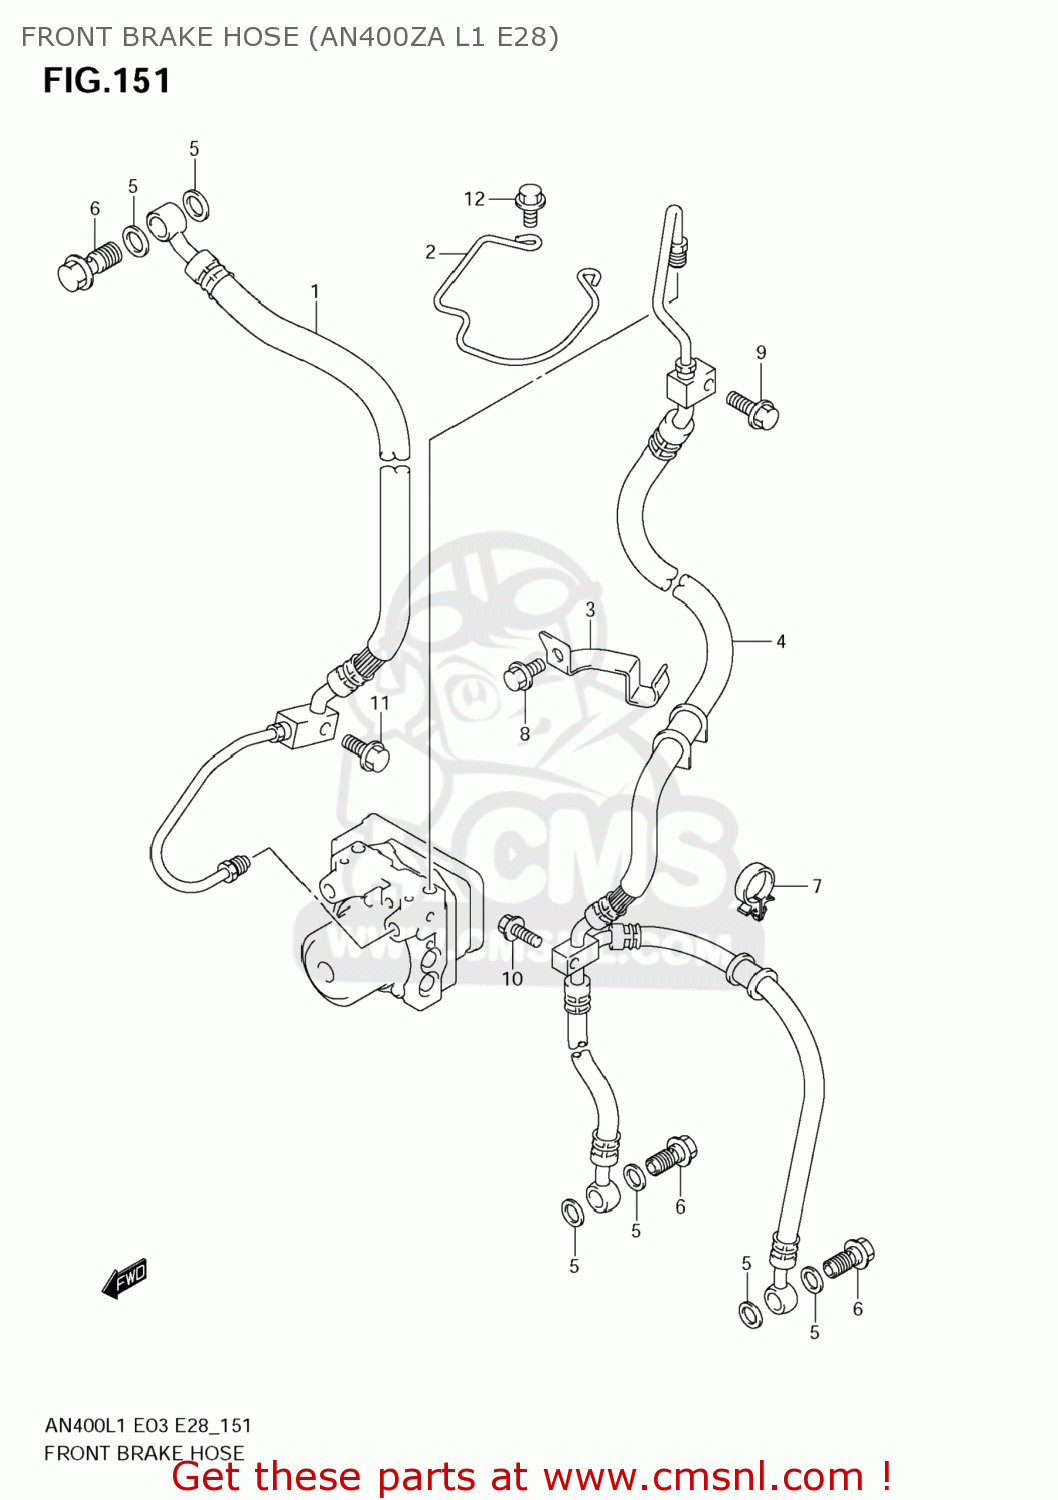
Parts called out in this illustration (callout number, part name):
1	HOSE ASSY,FR BRAKE NO.1
2	GUIDE,BRAKE HOSE
3	CLAMP,FR BRAKE HOSE NO.1
4	HOSE ASSY,FR BRAKE NO.2
5	WASHER(10X15X1.5)
6	BOLT UNION
7	CLAMP
8	BOLT
9	BOLT
10	BOLT
11	BOLT
12	BOLT
